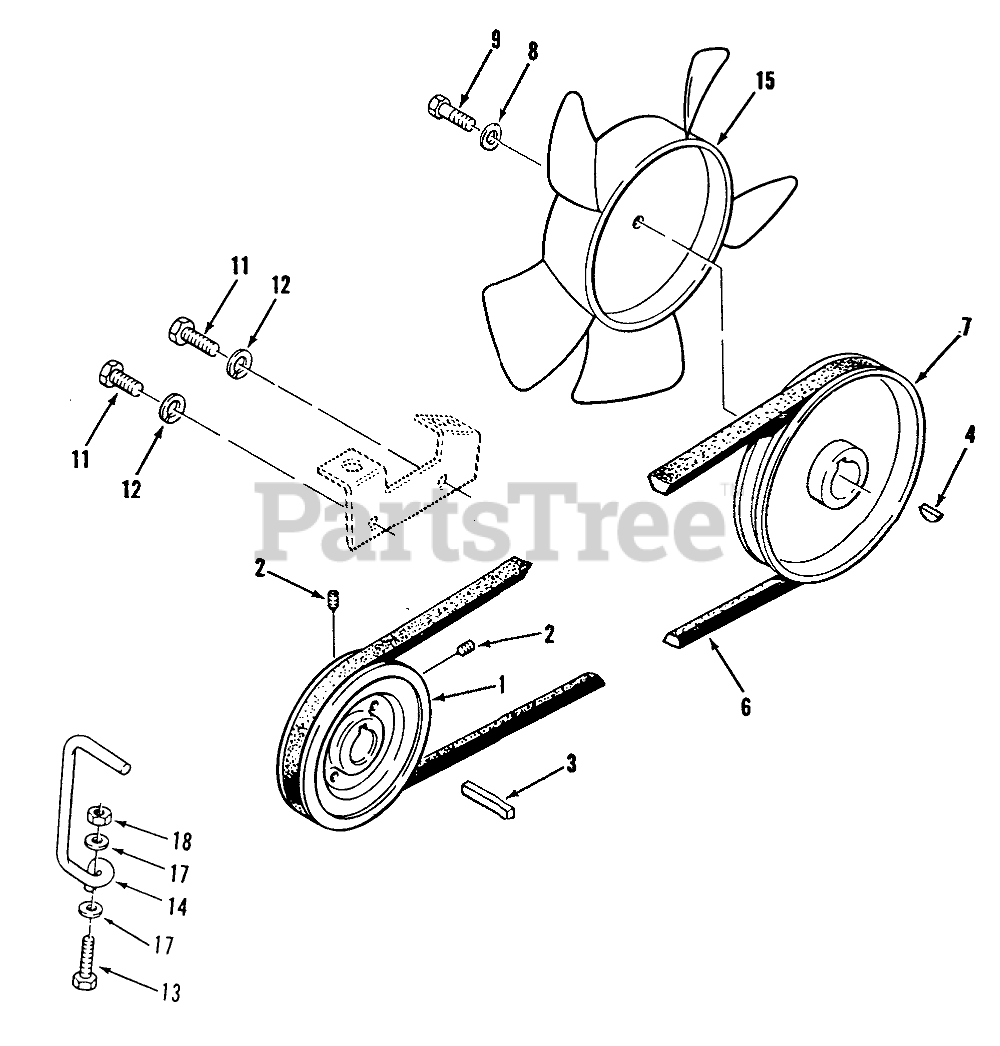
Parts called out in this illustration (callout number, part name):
1	PULLEY
2	Set Screw
4	KEY WOODR 1/8X1/2 DI
6	BELT-V
7	PULLEY
8	WASHER
9	HEX HD CAP SCREW -4
11	BOLT
12	LOCKWASHER
13	Bolt
14	GUIDE-BELT BOTTOM B
15	NYLON FAN-L-CW
17	Collar
18	Nut
